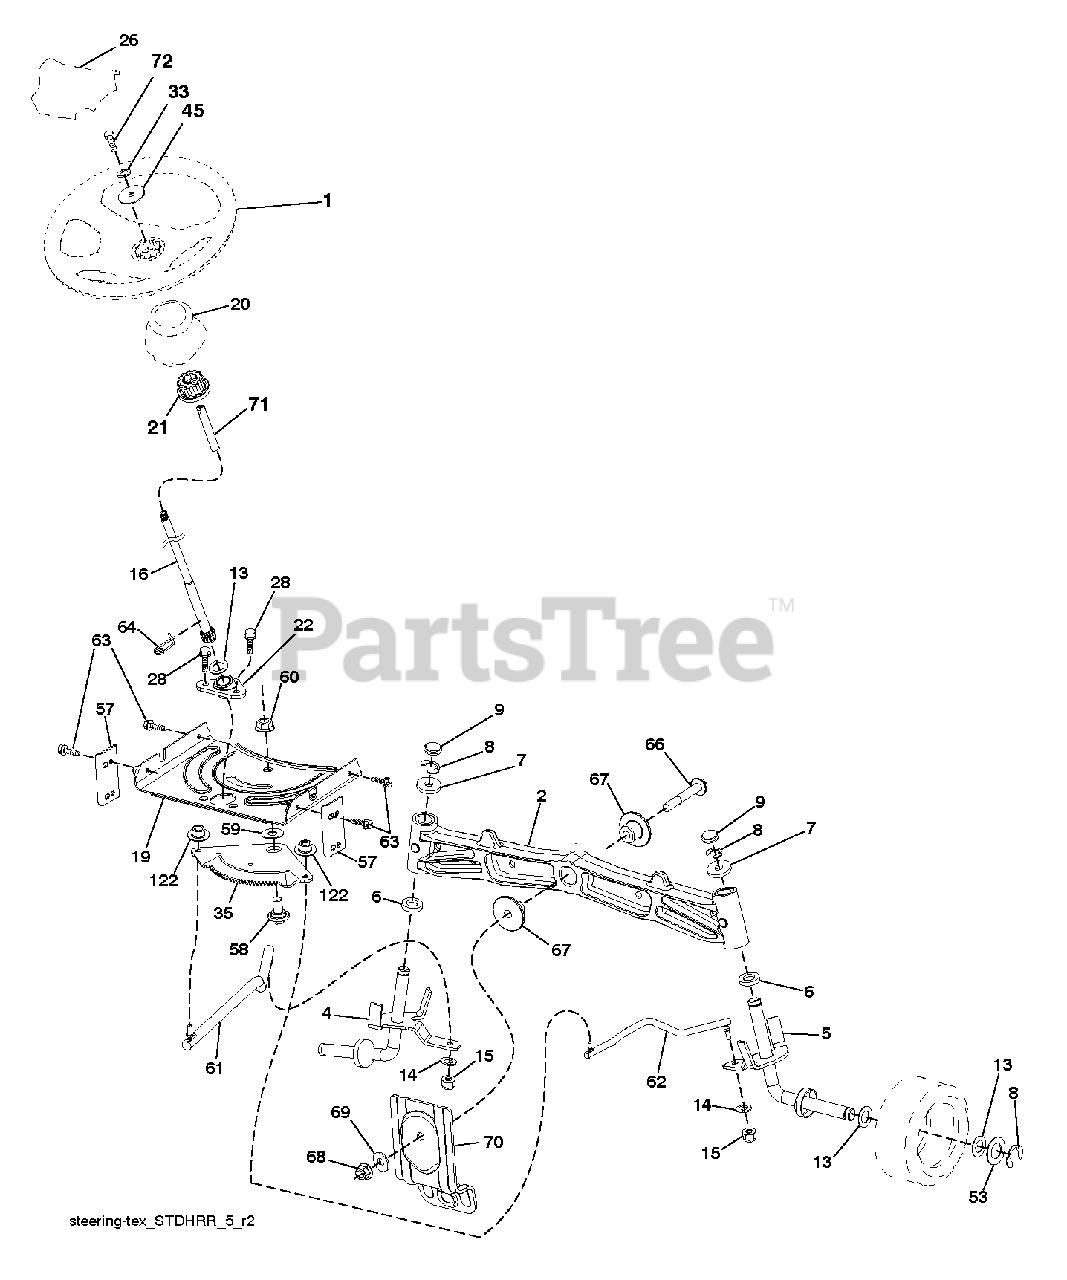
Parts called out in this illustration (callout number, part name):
1	WHEEL.STEERING.HARD.RIM.BLAC
2	AXLE.CAST.IRON
4	SPINDLE.WELDED.LH.15"TEX
5	SPINDLE.WELDED.RH.15"T
8	RING CLIP
9	CAP.SPINDLE.BLACK
14	WASHER, LOCK 3/8
15	NUT CROWNLOCK 3/8-24
16	SHAFT.STEER.3/4.NON-PLATED.TEX
19	PLATE.STEER.DDL.NLT/NG
20	BOOT STEERING BLACK
21	ADAPTER, WHEEL STNG..
22	STEERING.SUPT.LOWER.
26	INSERT, WHEEL STEERING
28	SCREW, 3/8-16X3/4
33	LOCKWASHER
35	GEAR.SECTOR.PLATE.DDL.
45	WASHER.11/32
53	WASHER.HARDENED
57	BRACKET.UPSTOP.TEX
58	BOLT.SHOULDER.SECTOR.P
59	WASHER.THURST.SECTOR.S
60	NUT FLANGE LOCK 5/8-11
61	DRAGLINK.LH.BALLSTUD.D
62	DRAGLINK.RH.BALLSTUD.D
63	SCREW
64	RETAINER.CLIP.SPRING.S
66	BOLT HEX FGHD 7/16-14 X 3 SERR
67	BUSHING.PM.FRONT AXLE
68	NUT.LOCK.FLANGE.7/16
69	WASHER.1.5X.505X.118
70	BRKT.DECK.SUSPENSION.F
71	SHAFT.EXTEN.STRG.SPLINE
72	BOLT 5/16-18 X 4 W/PATCH
122	CAP.GEAR.SECTOR.TEX
